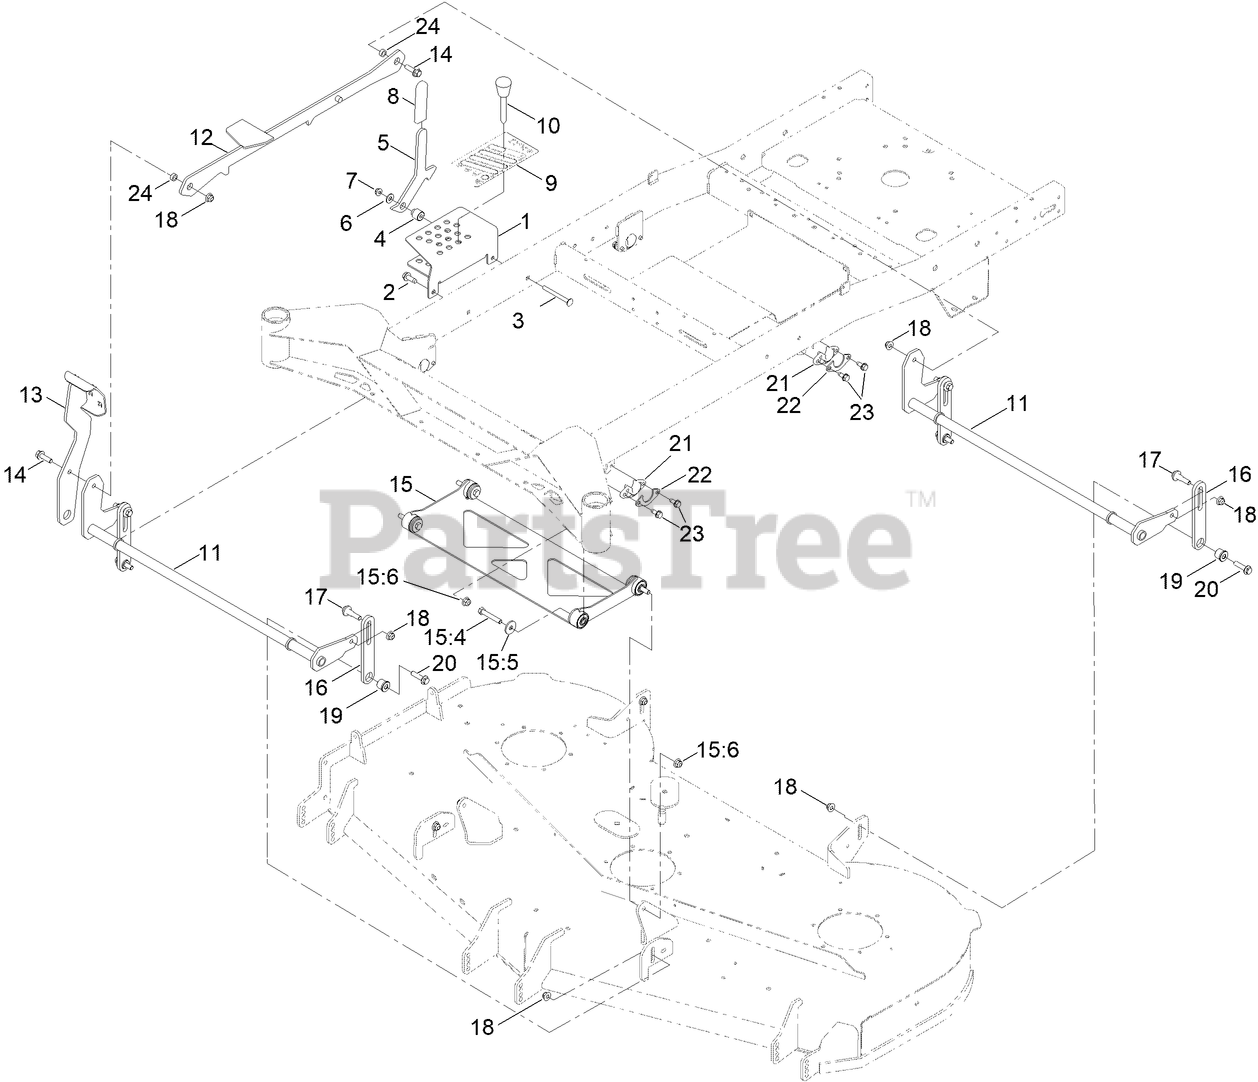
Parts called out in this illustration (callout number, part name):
1	BRACKET-HOC
2	SCREW-HWH
3	SCREW-CARR
4	SPACER-STEPPED
5	PLATE-TRANSPORT LOCK
6	WASHER-PLAIN
7	NUT-HF
8	GRIP-HANDLE
9	DECAL-HOC, TITAN
10	HOC PIN ASM
11	PIVOT ASM-DECKLIFT [BLK-TXT]
12	LINK ASM-HOC [BLK-TXT]
13	PEDAL ASM [BLK-TXT]
14	SCREW-HHF
15	DECK STRUT ASM
15:4	SCREW-HH
15:5	WASHER
15:6	NUT-HF, NI
16	LINK-HOC
17	BOLT-SHOULDER
18	NUT-HF, NI
19	BUSHING-DECK LIFT
20	SCREW-HHF
21	BEARING-FLANGE
22	GUSSET-DECK LIFT
23	SCREW-HWHTF
24	SPACER
